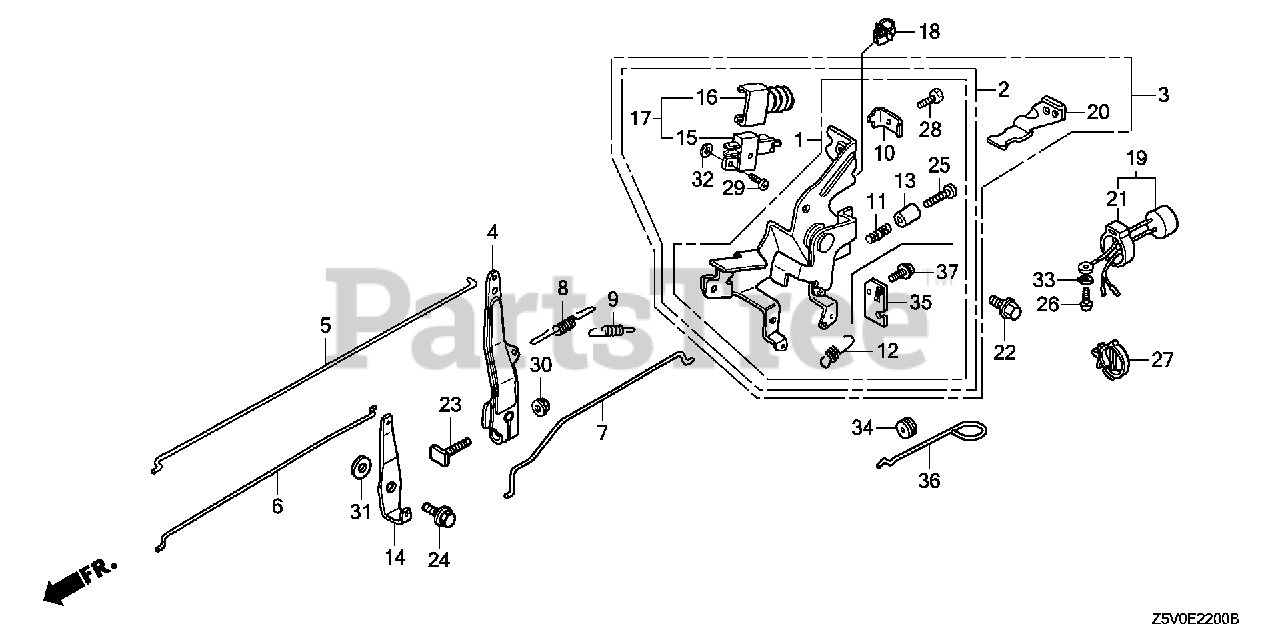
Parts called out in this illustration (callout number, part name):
2	CONTROL ASSY.
4	ARM, GOVERNOR
5	ROD, GOVERNOR
6	ROD, CHOKE
7	ROD, JOINT
8	SPRING, GOVERNOR
9	SPRING, GOVERNOR PRIMARY
10	HOLDER, CABLE
11	SPRING, CONTROL ADJUSTING
12	SPRING, CABLE RETURN
13	COLLAR, STOPPER
14	LEVER, CHOKE JOINT
15	SWITCH ASSY., ENGINE
16	COVER, SWITCH
17	SWITCH ASSY., ENGINE STOP
22	BOLT, FLANGE (6X12) (CT200)
23	BOLT, GOVERNOR ARM
24	BOLT, FLANGE (6MM)
25	SCREW, RECESSED (5X20)
28	BOLT, RECESSED (5X14)
29	SCREW, PAN (4X14)
30	NUT, FLANGE (6MM)
31	WASHER, PLAIN (6MM)
32	WASHER, SPRING (4MM)
